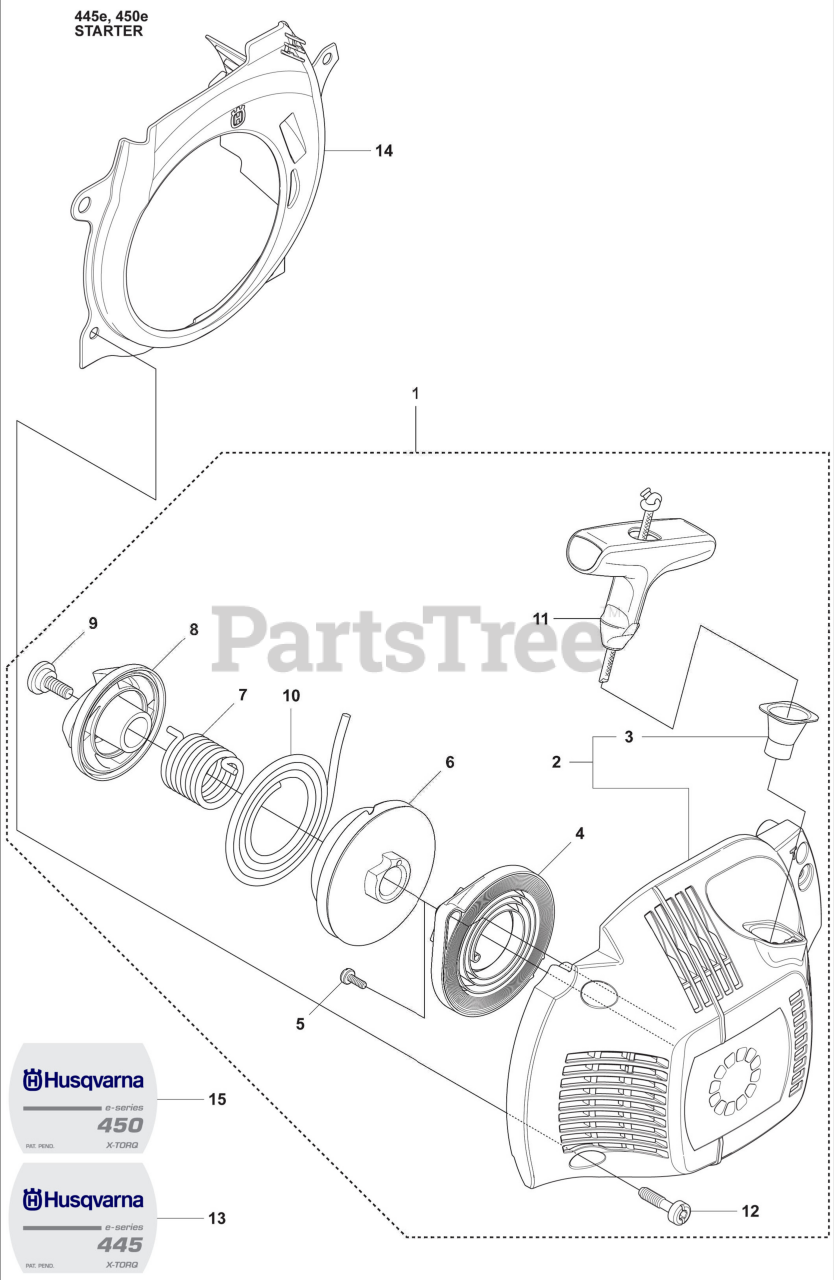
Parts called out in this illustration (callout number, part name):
1	Starter Assembly
2	Starter Housing
4	Return Spring
6	Starter Pulley
8	Starter Hub, EPS
9	Shoulder Screw
10	Starter Rope
12	Recoil Starter Screw
13	Label
14	Air Cooling Conductor
15	Label
